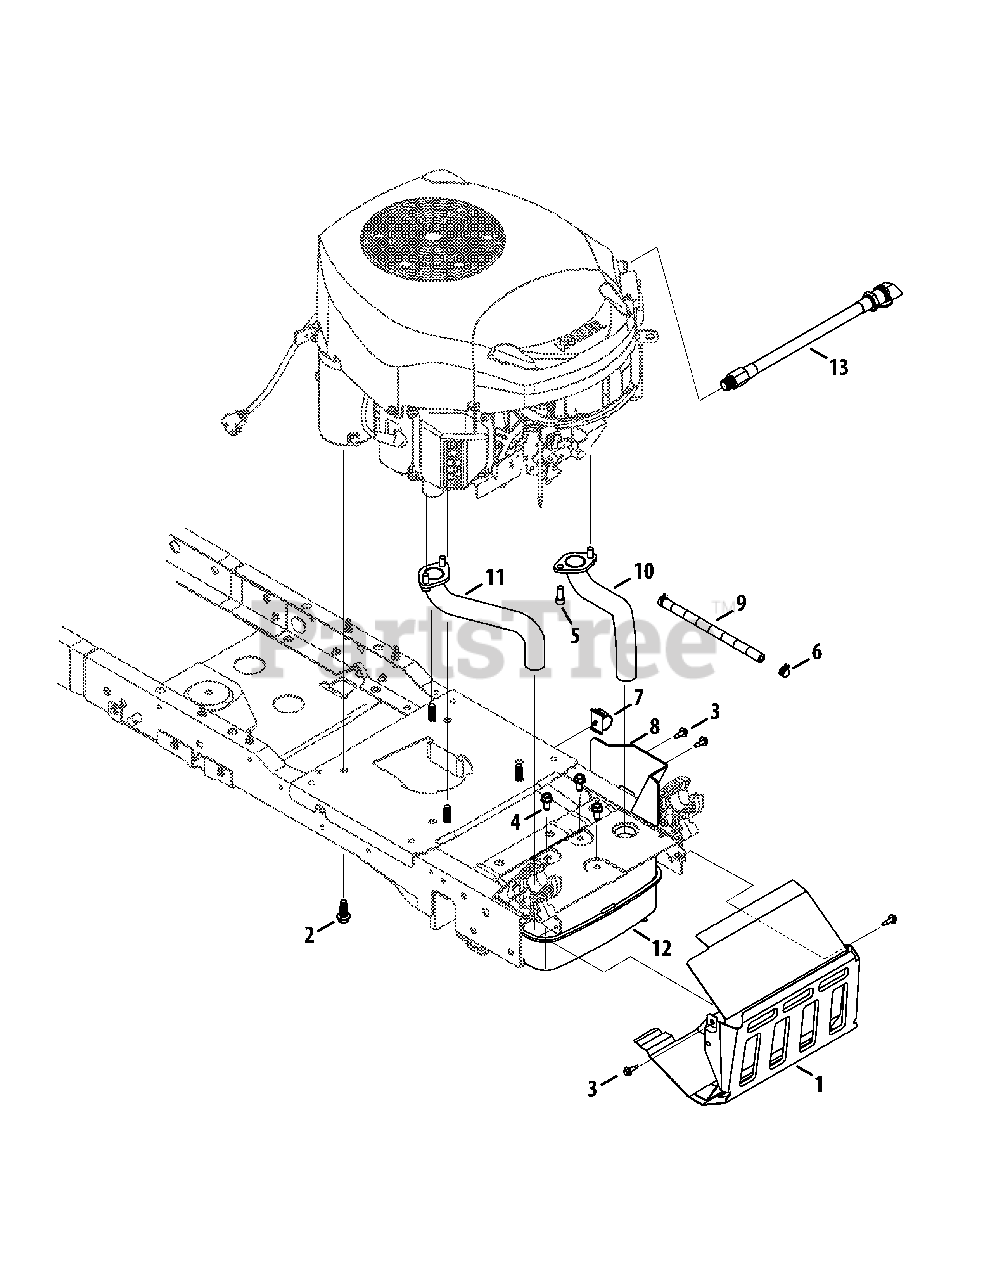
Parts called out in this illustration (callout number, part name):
1	Shield Ass’y, Muffler
2	Screw, Self-tapping, 3/8-16, 1.0
3	Screw, M6-1 x .625
4	Screw, Self-tapping, M8-1.25, .750
5	Screw, Sokt Head, 5/16-18, .750
6	Clamp, Hose, .490 Dia.
7	Push Mount Wire Clip, .750
8	Muffler Shield
9	Hose, Fuel, Low Permeation, 1/4
10	Exhaust Pipe, LH
11	Exhaust Pipe, RH
12	Muffler, Kohler
13	Drain, Oil
